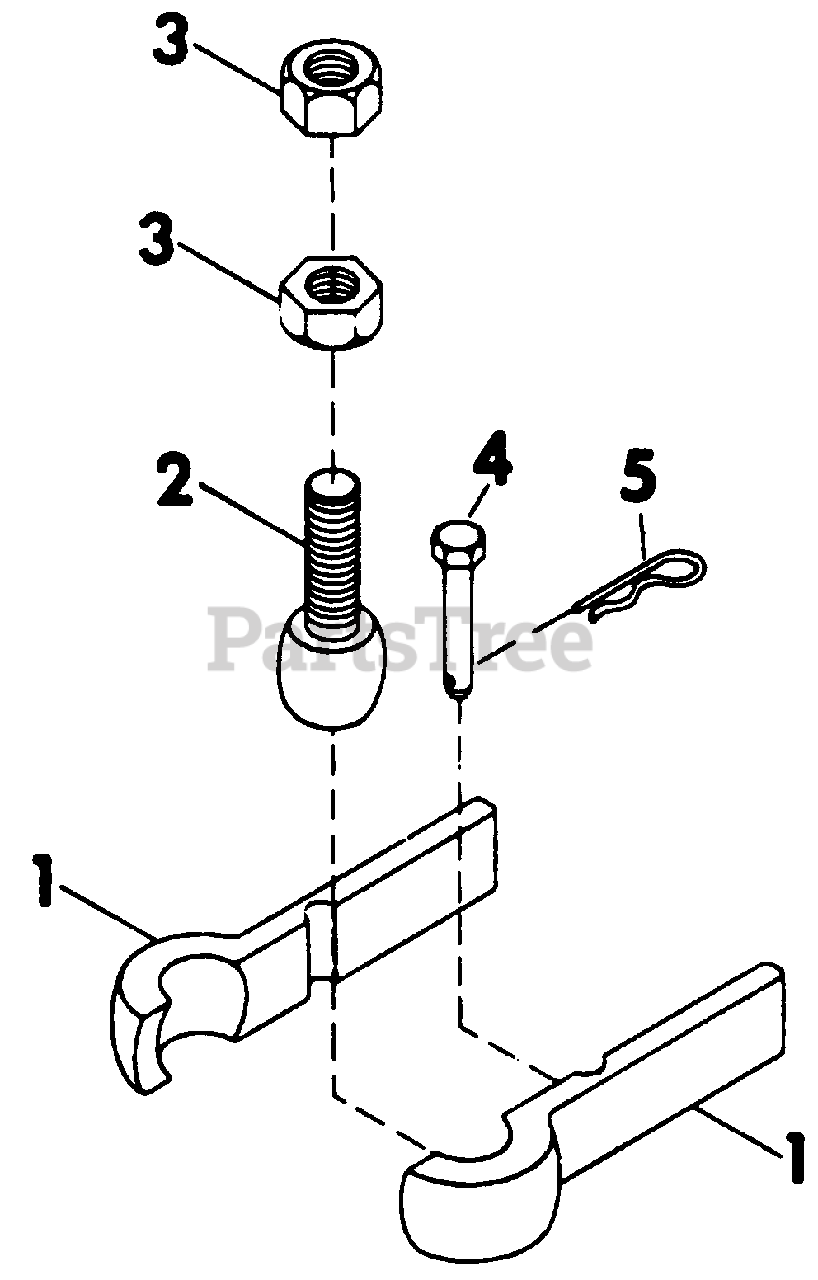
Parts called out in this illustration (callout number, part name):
1	SPLIT SOCKET
2	BALL STUD
3	5/8" - 18 HEX JAM NUT
4	DRAWBAR PIN
5	HAIR PIN COTTER
